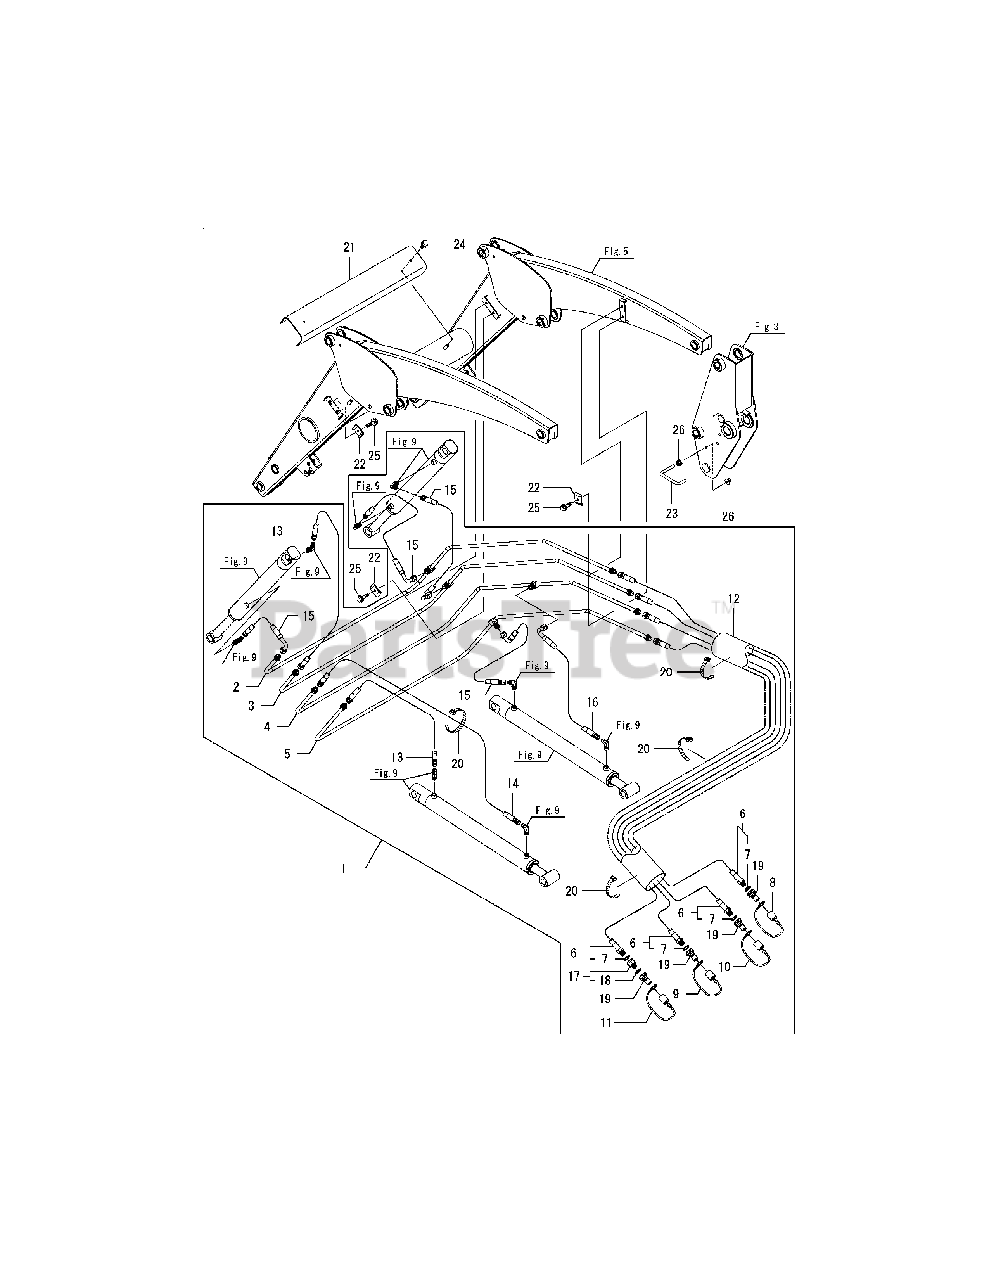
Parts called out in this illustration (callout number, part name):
1	HYDRAULIC LINE ASSY
5	HP PIPE, RAISE
6	HP HOSE,INTAKE RED
8	DUST PLUG,M RED
9	DUST PLUG,M BLUE
10	DUST PLUG,M YELLOW
11	DUST PLUG,M GREEN
12	COVER,HOSE INTAKE
13	HP HOSE 3/8-500 CMP
14	HP HOSE 3/8-1100 CMP
15	HP HOSE,R-F 500 CMP
16	HP HOSE,R-F 650 CMP
17	FITTING,ORIFICE
19	COUPLER,QUICK 3/8M
24	BOLT M 8X 16 PLATED
25	BOLT M 8X 30 PLATED
